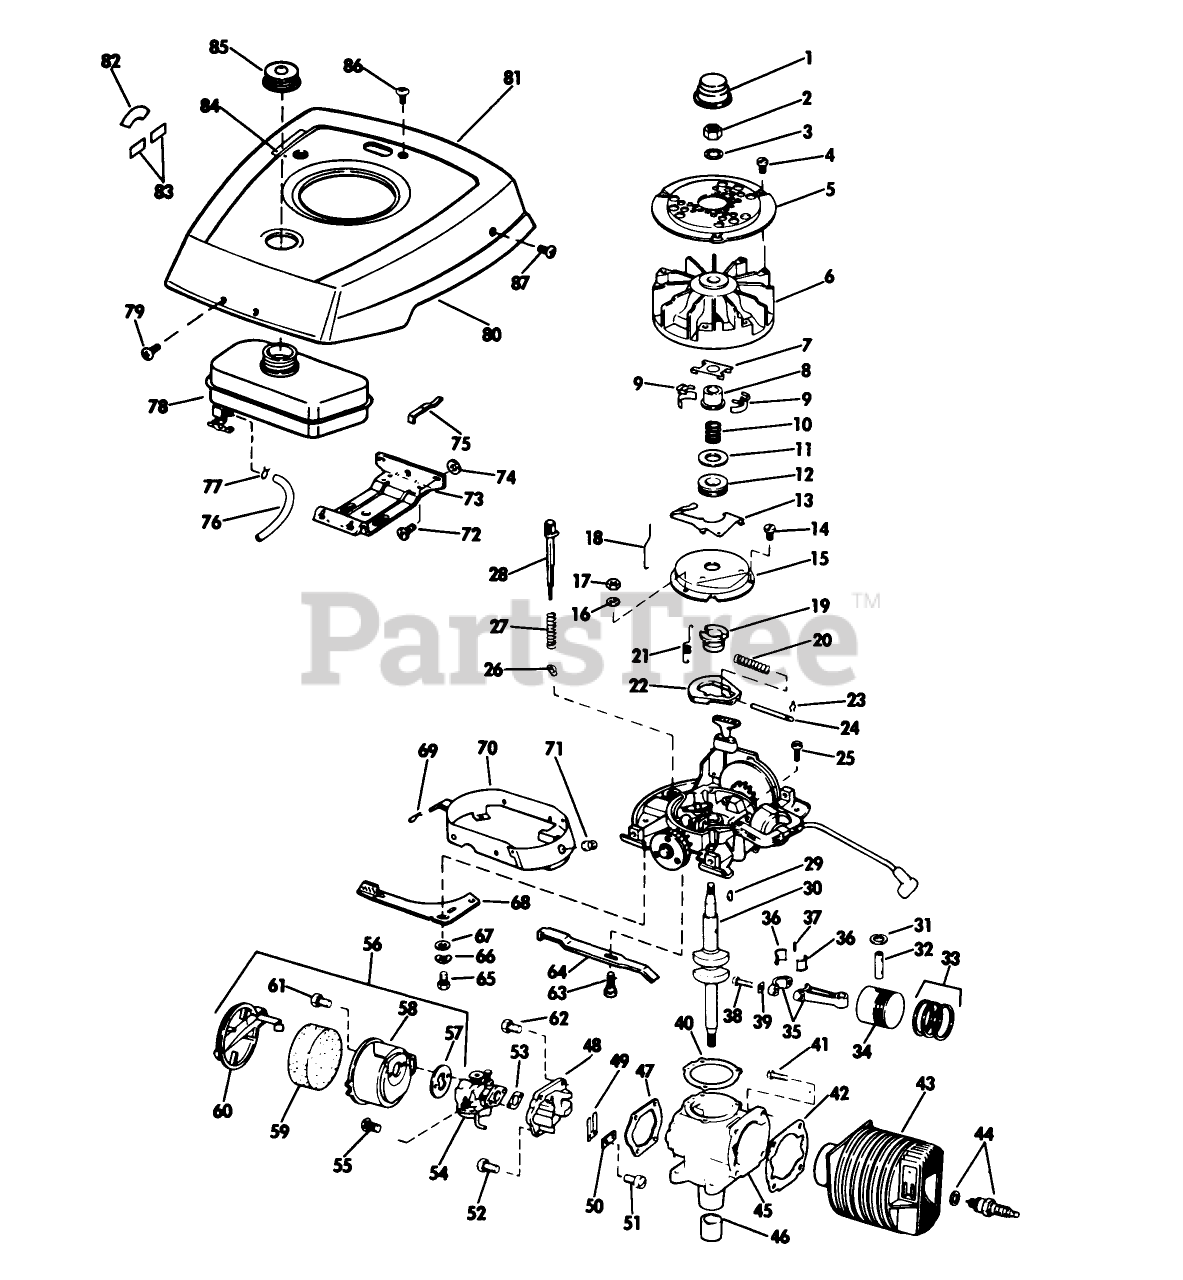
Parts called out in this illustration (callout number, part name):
8	COLLAR S
10	SPRING S
12	THRUST COLLAR S
13	LEVER-GOVERNOR S
14	SCREW S
15	DUST COVER S
19	SPARK ADV. S
20	SPARK ADV. SPRING S
22	FLYWEIGHT S
23	SPARK ADJ. SPRING
24	PIN,SPARK ADV. S
27	SPRING S
31	RING-RETAINING
36	LINER ASM
40	GASKET S
42	GASKET S
50	PLATE-BACKUP, REED
52	SCREW S
53	GASKET S
59	AIR FIL.ELEM S
61	SCREW S
62	SCREW S
71	NUT-CLIP
72	SCREW S
76	GAS LINE
77	CLAMP - HOSE S
86	SCREW F
87	SCREW S
